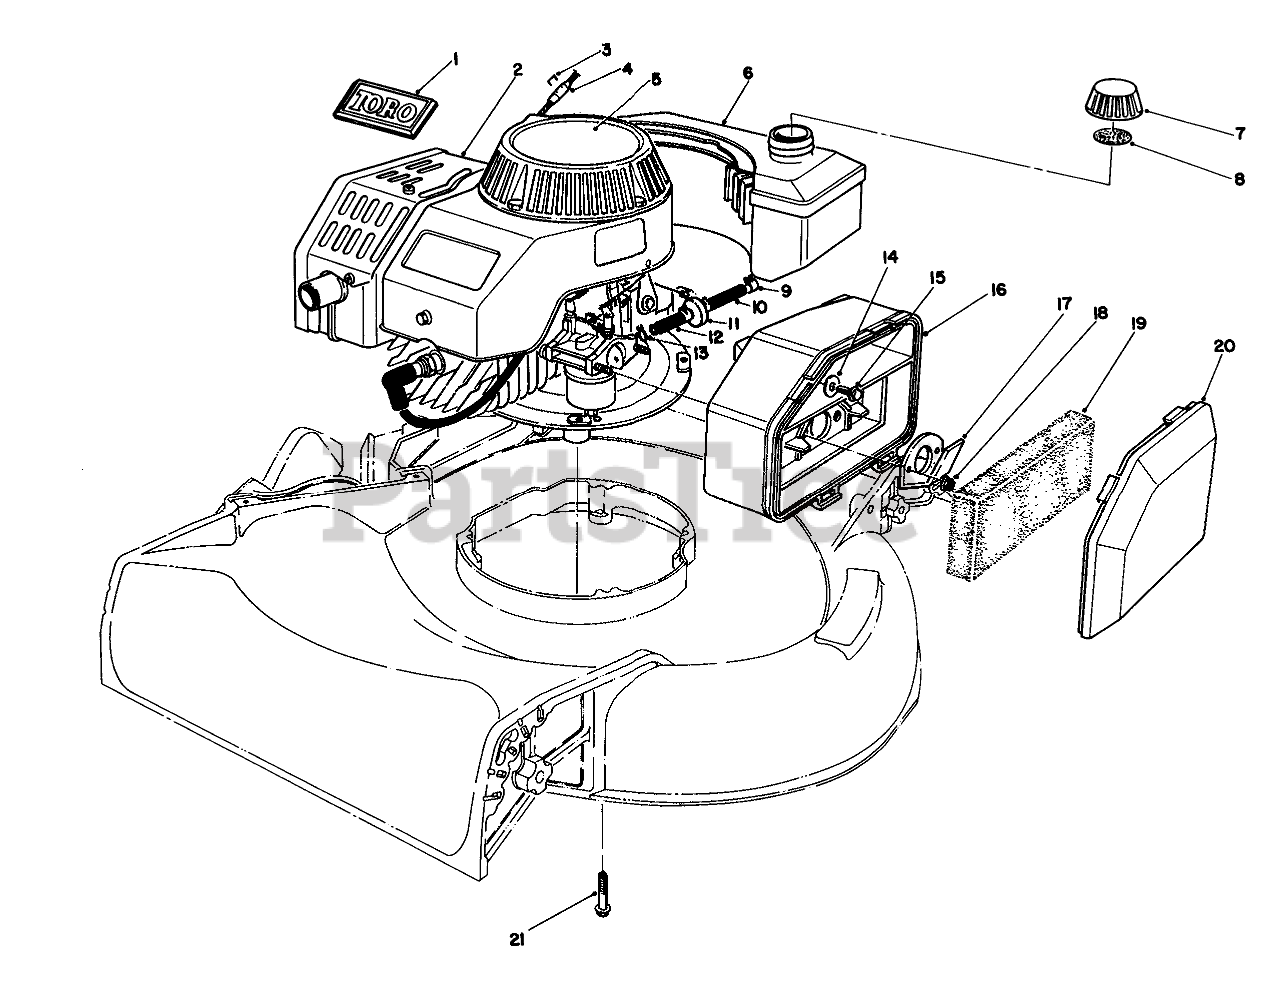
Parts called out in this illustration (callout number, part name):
1	TORO LOGO PLT
2	Engine
3	Staple
4	STOP-ROPE
5	DECAL
6	Fuel Tank Assembly
7	Gas Cap Assembly (Incl. Ref. #8)
8	GAS CAP GASKET
9	CLAMP-FUEL LINE
10	HOSE-FUEL
11	FILTER-FUEL
12	HOSE-FUEL
13	CLAMP-HOSE
14	WASHER-FLAT
15	SCREW-HH
16	AIR CLEANER
17	SPIT BACK DEFLECTOR
18	NUT-LOCK
19	FILTER
20	AIR CLEANER COVER
21	FLG SCREW,3/8-16X2.000
